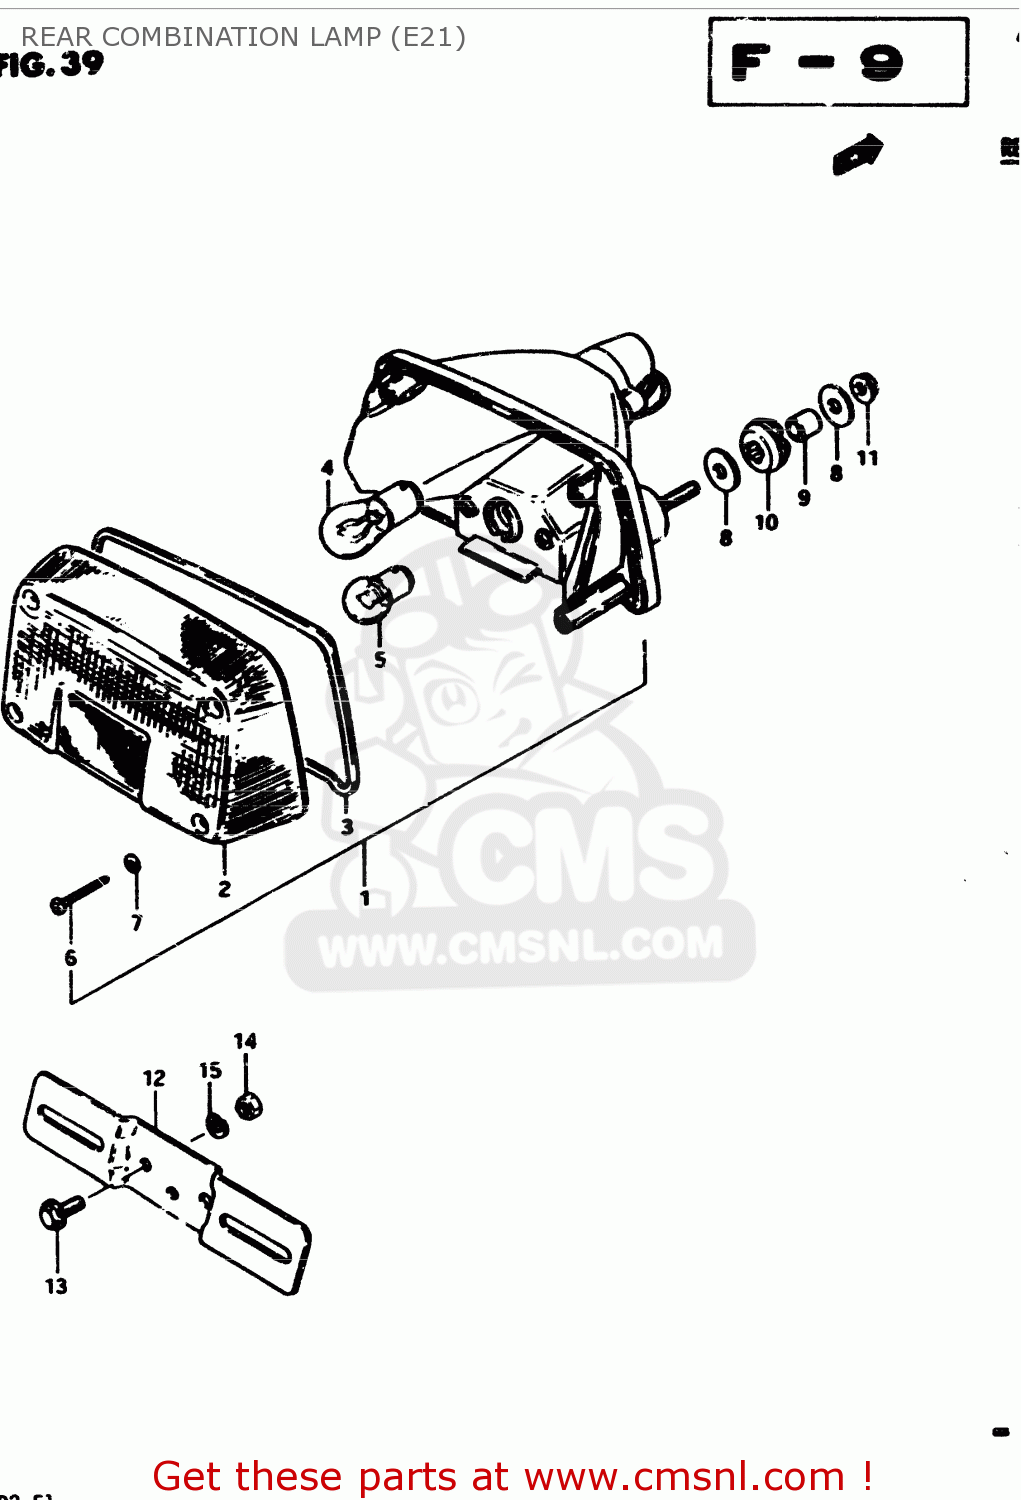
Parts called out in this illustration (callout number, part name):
1	LAMP ASSY, REAR COMBINATION
2	LENS,RR COMBI
3	GASKET
4	BULB(12V21/5W)
5	BULB
6	SCREW
7	GASKET (NAS)
8	WASHER
9	SPACER (6.8X10X11.5)
10	CUSHION
11	NUT 6MM
12	BRACKET, LICENSE PLATE
13	BOLT
14	NUT
15	LOCK WASHER
